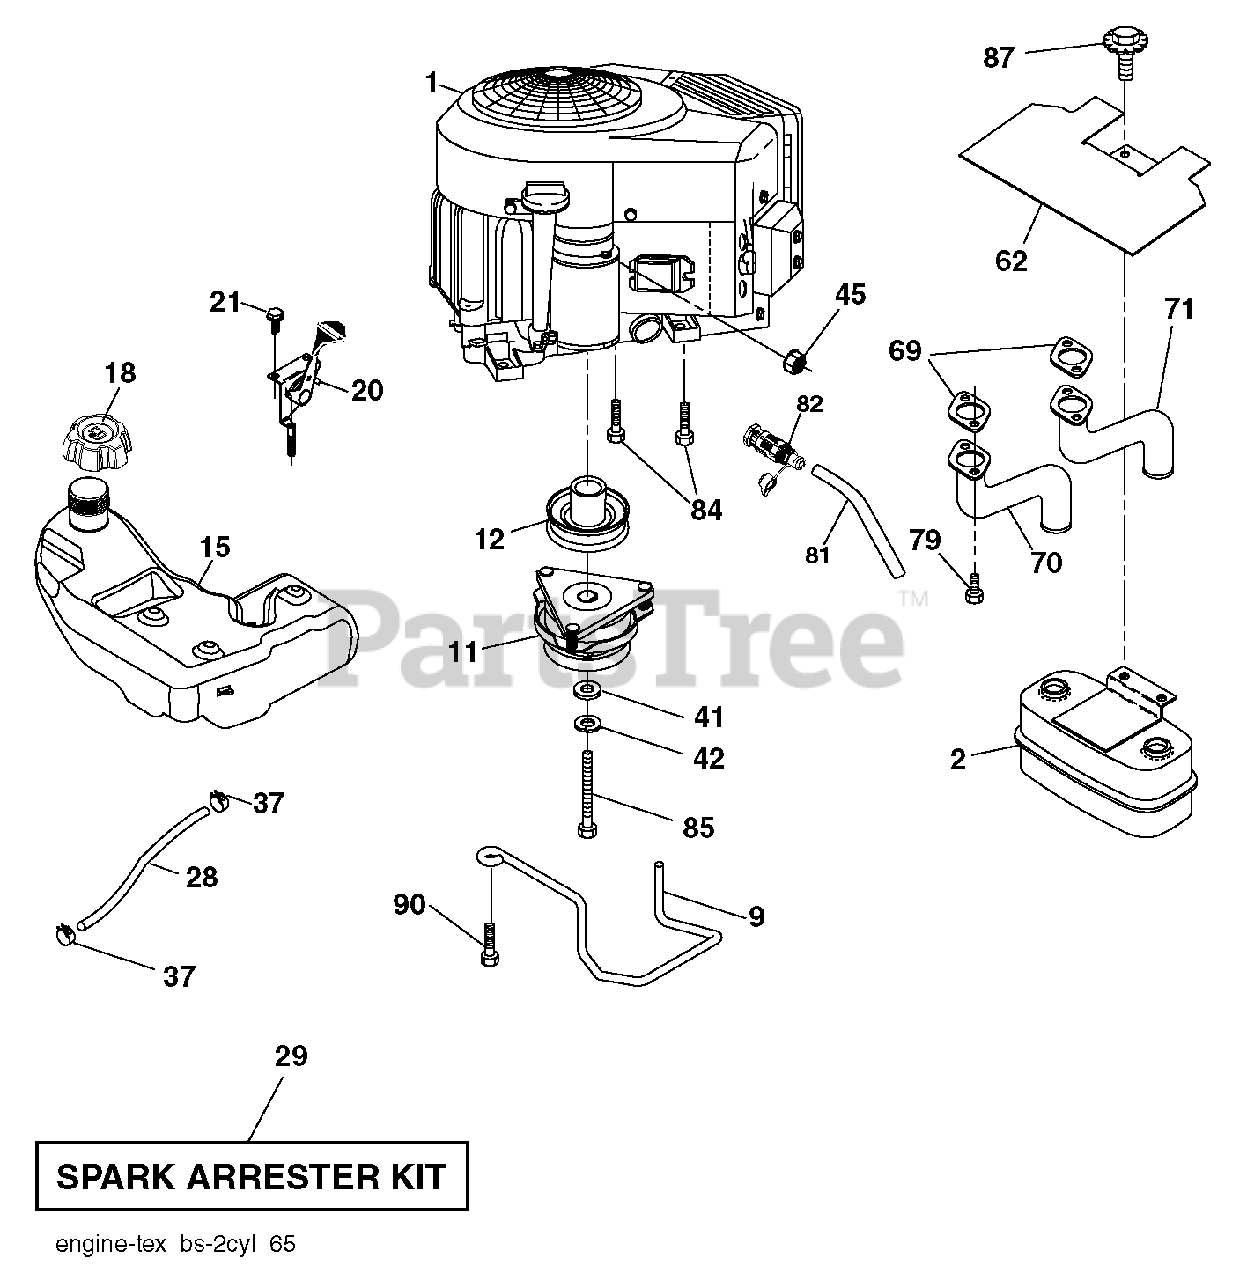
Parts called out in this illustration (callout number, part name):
2	MUFFLER.TWIN.CYL.LOW.TONE
9	KEEPER.BELT.ENGINE.4.25"
11	CLUTCH ELECTRIC
12	PULLEY ENGINE
15	TANK.FUEL.4GAL
18	CAP.ASM.FUEL.TANK.3"BLACK
20	CONTROL.TH/CK.COBRA.B&S.TWN.
21	SCREW.#10 X 0.750.BOS THREAD
28	Fuel Line
29	ARRESTER SPARK (OPTIONAL)
42	LOCKWASHER
45	NUT
62	SHIELD.HEAT.MUFFLER
69	GASKET.MUFFLER
70	EXHAUST TUBE LH *SUBS/2*
71	EXHAUST TUBE RH
79	SCREW.SOCKET.HEAD.5/16-18
81	TUBE, DRAIN OIL ASM.
82	VALUE.OIL.DRAIN
85	BOLT HEX 7/16-20 X 3.75 GR. 5
87	BOLT.5/16-18UNCX1.W/SEMS.BLK
90	SCREW 3/8-16X1
